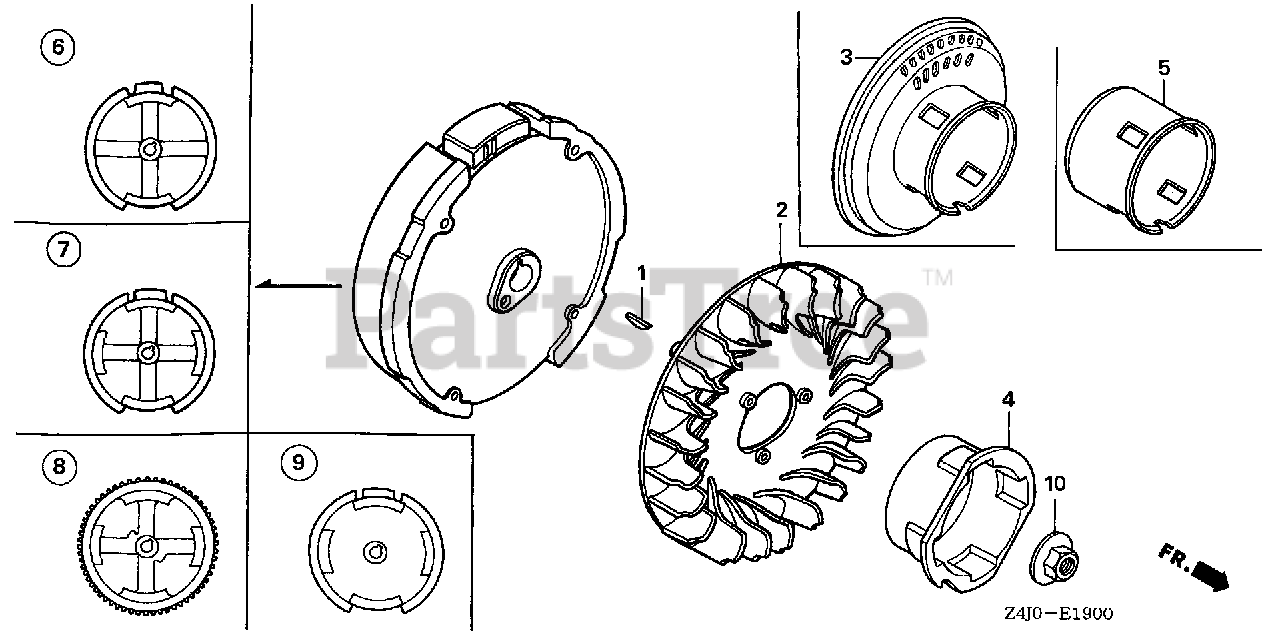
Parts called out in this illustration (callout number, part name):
1	KEY, SPECIAL WOODRUFF (25X18)
2	FAN, COOLING
5	PULLEY, STARTER
6	FLYWHEEL (STD)
10	NUT, SPECIAL (14MM)
